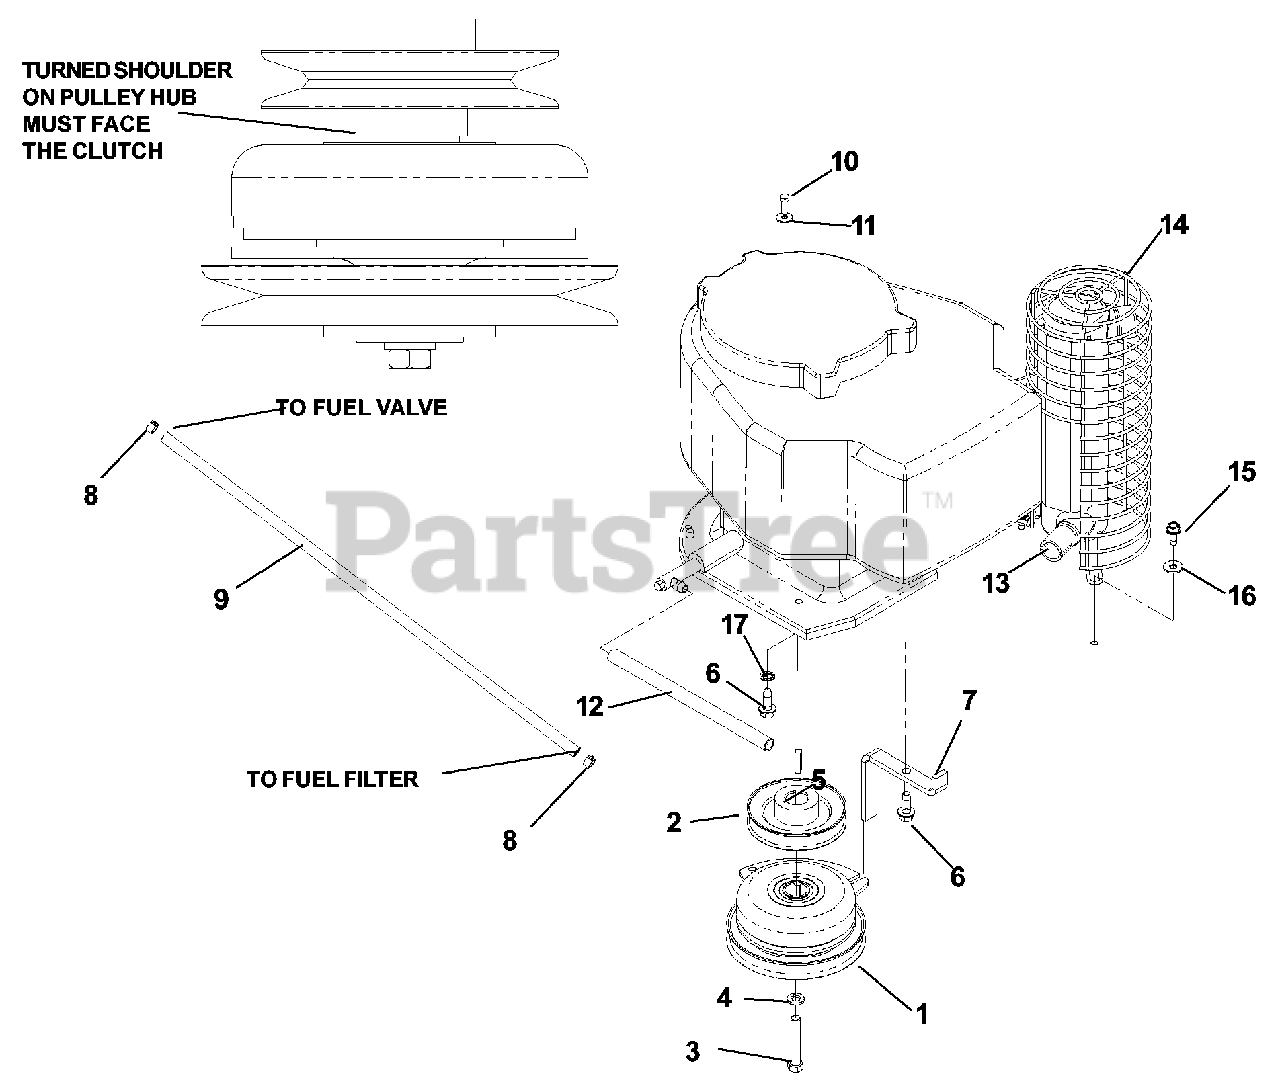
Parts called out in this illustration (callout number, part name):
1	CLUTCH 125 FT/LB
3	HCS 7/16F X 2 1/2
4	LOCKWASHER, 7/16
5	KEY, 1/4" SQ. X 1 1/8"
6	BOLT 3/8-16 X 1, THREAD FORMING
7	CLUTCH TIE DOWN
8	HOSE CLAMP
9	FUEL LINE, 24"
10	HCS M6-1.0 X 20
11	WASHER, 1/4 FLAT
12	OIL DRAIN HOSE
14	WIRE GUARD
15	BOLT, 5/16-18 X 3/4, THREAD FORMING
16	WASHER, 5/16
17	WASHER, 3/8, INTERNAL TOOTH
